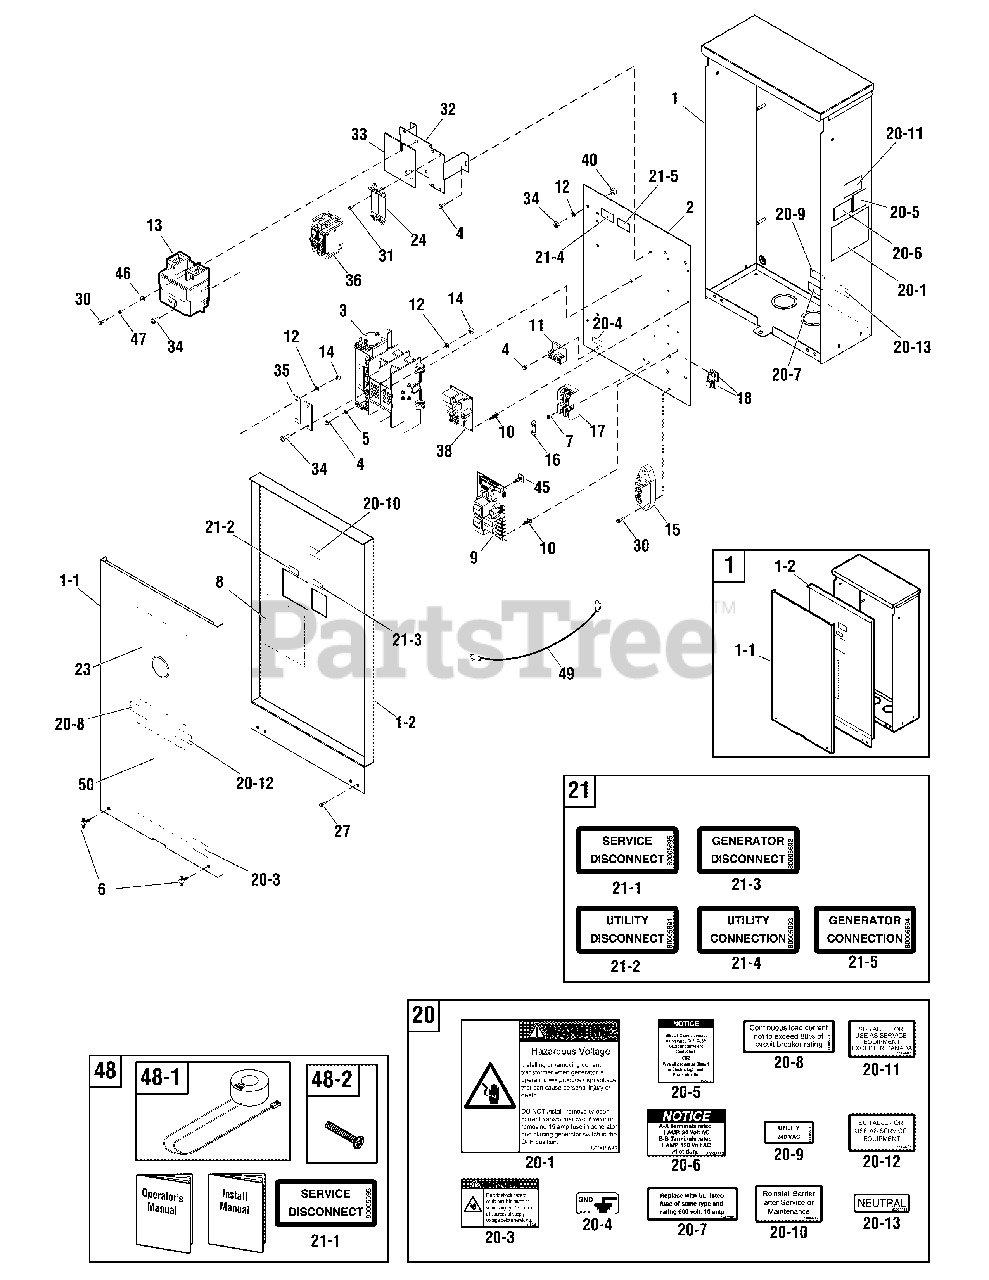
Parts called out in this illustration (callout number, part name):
1	ENCLOSURE
2	BACK PANEL
3	SWITCH, Transfer
4	* TRILOBULAR, #10-32 x 1/2
5	* WASHER, External Tooth, #10
7	* SCREW, Hex Head, Trilobular, #6-32 x 3/8
9	BOARD, Circuit
11	LUG
12	* WASHER, Lock, 1/4
13	BREAKER, Circuit, 200A
14	* NUT, 1/4-20
16	FUSE
20	DECAL SHEET - WARNINGS
20-1	DECAL, Warning Voltage
20-3	DECAL, Warning Shock
20-4	DECAL, Ground
20-5	DECAL, Notice
20-6	DECAL, Contacts Rated
20-7	DECAL, Fuse, 10 Amp
20-8	DECAL, Breaker, Circuit
20-9	DECAL, Sensing, Utility
20-10	DECAL, Reinstall After
20-11	DECAL, Not Suitable
20-12	DECAL, Suit. as Service Equip.
20-13	DECAL, Neutral
21	DECAL SHEET-CONNECTIONS
21-1	DECAL, Service Disconnect
21-2	DECAL, Disconnect Utility
21-3	DECAL, Gen Disconnect
21-4	DECAL, Connection, Utility
21-5	DECAL, Connect Gen
27	TRILOBULAR, #10-32 x 3/8"
30	* SCREW, Hex Head, Trilobular, #10-32 x 3/4
31	* SCREW, Hex Head, Trilobular, 8-32 x 3/8
34	* SCREW, Phillips Head, 1/4-20x 3/4
35	BAR, Bus
36	BREAKER, Circuit, 100A
40	SPACER
46	* WASHER, Flat, #10
47	* WASHER, Lock, #10
48	KIT, Manual
48-1	CURRENT TRANSFORMER
49	WIRE
